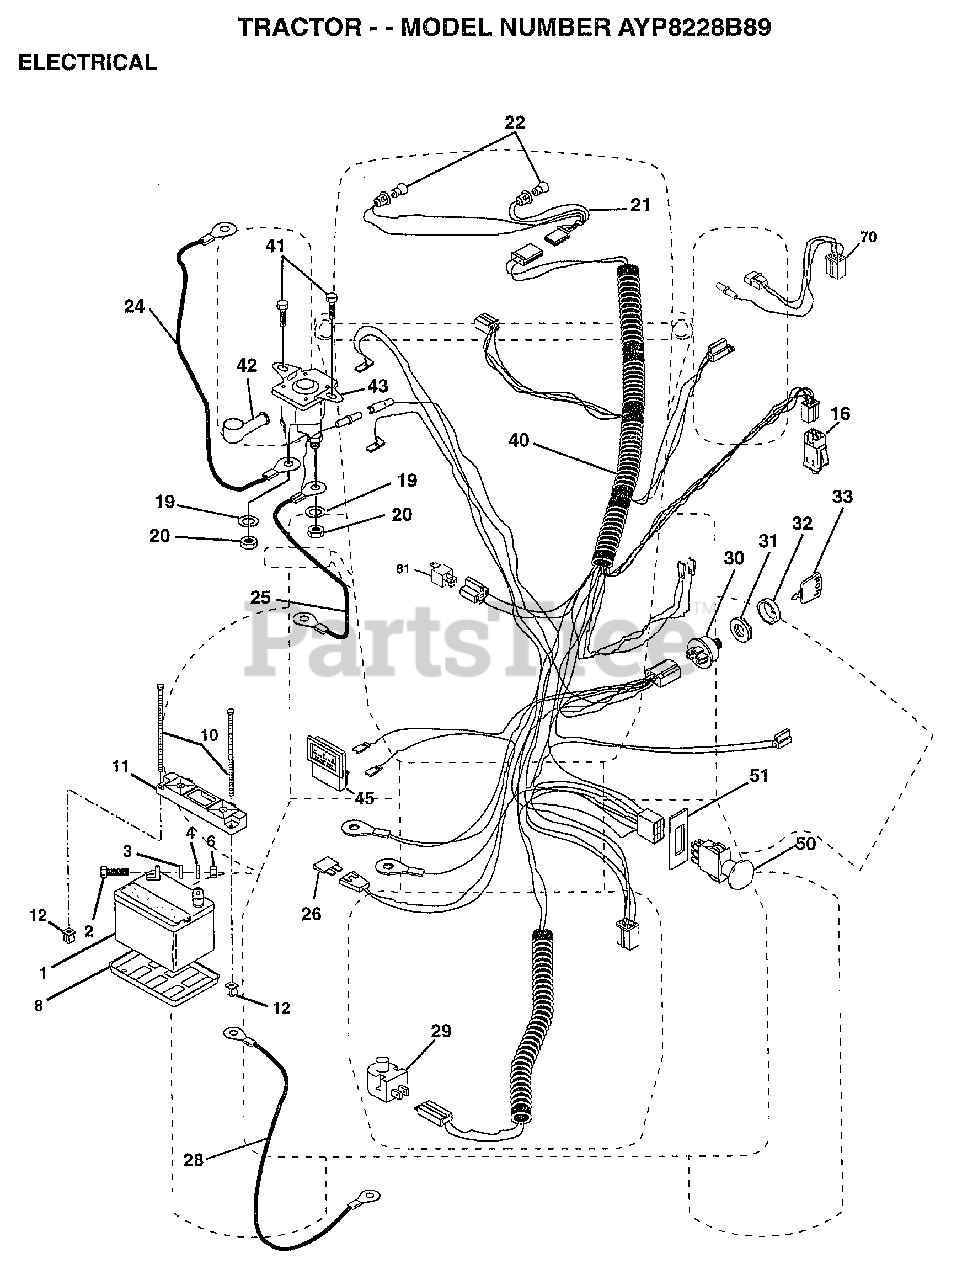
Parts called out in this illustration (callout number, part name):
3	LOCKWASHER
4	WASHER
8	"TRAY T, BATTERY"
11	HOLDDOWN BATTERY
16	SWITCH INTERLOCK
20	NUT
21	"HARNESS,LIGHT SOC"
22	HEADLAMP BULB
24	CABLE-BATTERY T
25	CABLE.6GA.12.5.
26	FUSE HYT
28	CABLE T
29	SWITCH.PLUNGER
30	SWITCH IGN 4POS
31	NUT IGNITION
32	COVER KEY SWITCH
33	KEY
40	HARNESS.IGNITON
41	SCREW
45	AMMETER
50	PTO SWITCH.BLK
51	RING RETAIN PTO
70	HARNESS.ENGINE
81	RELAY ASSY T
